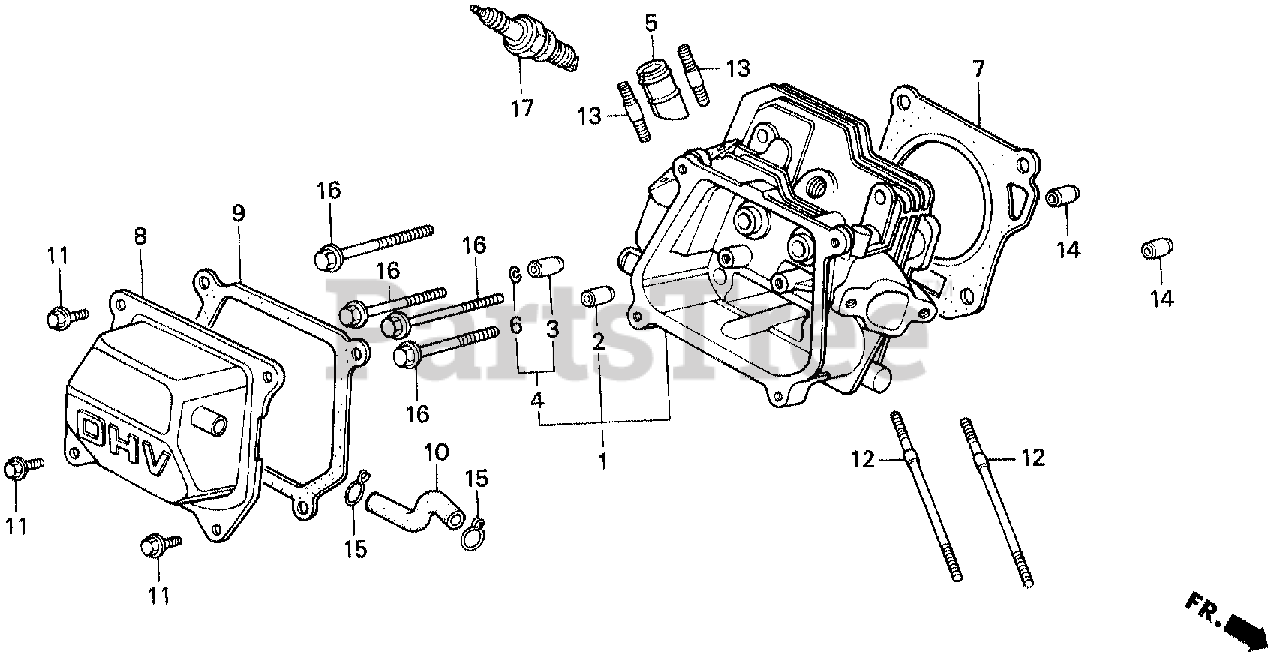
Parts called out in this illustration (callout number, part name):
1	CYLINDER HEAD
2	GUIDE, VALVE (OS)
4	GUIDE, EX. VALVE (OS)
6	CLIP, VALVE GUIDE
7	GASKET, CYLINDER HEAD
8	COVER, HEAD
9	GASKET, CYLINDER HEAD COVER
10	TUBE, BREATHER
11	BOLT, FLANGE (6X13)
12	BOLT, STUD (6X109)
13	BOLT, STUD (8X32)
14	PIN A, DOWEL (10X16)
16	BOLT, FLANGE (8X60)
17	SPARK PLUG (BPR6ES) (NGK)
17	SPARK PLUG (W20EPR-U) (DENSO)
